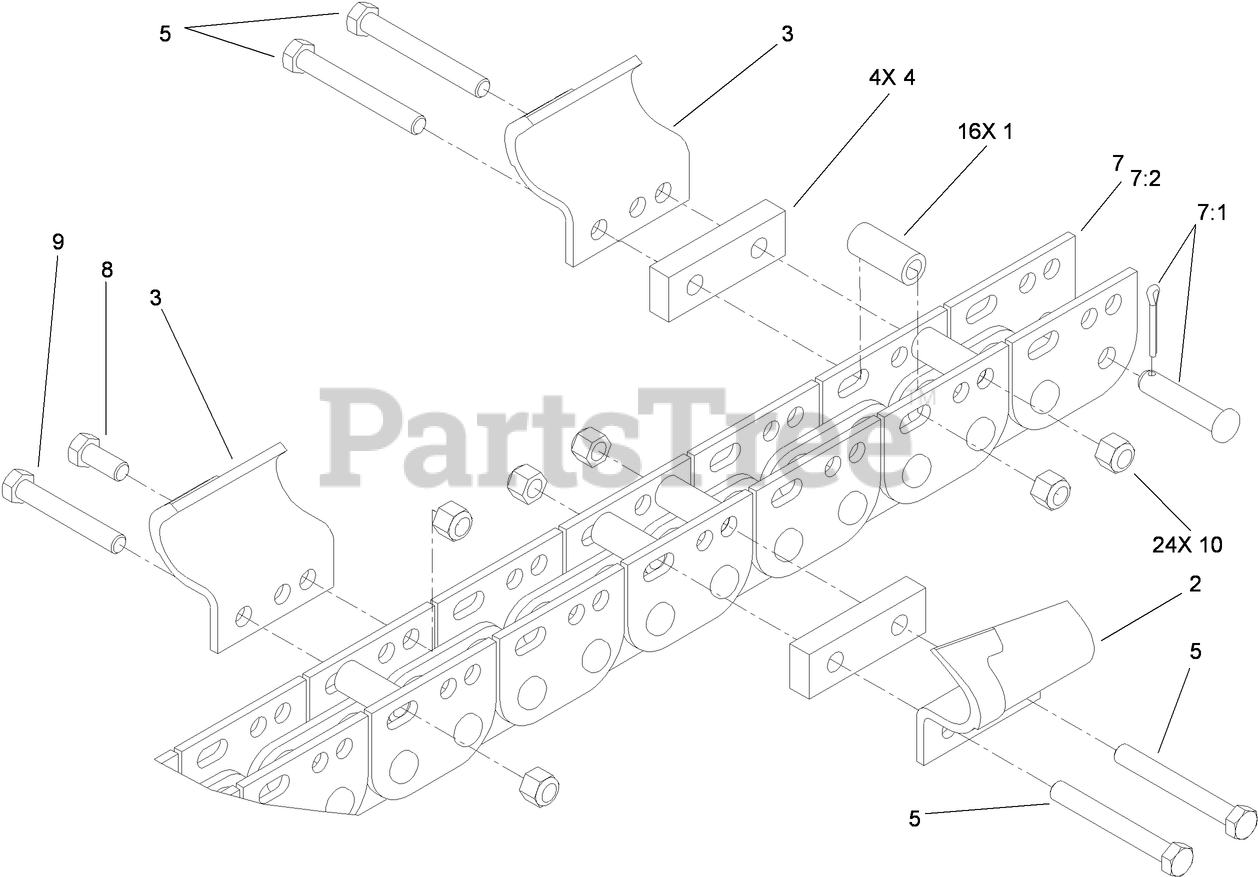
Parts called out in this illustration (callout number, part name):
1	SPACER-TUBE
2	TOOTH-SOIL, LH
3	TOOTH-SOIL, RH
4	SPACER-CUT, 5 INCH
5	SCREW-HH
7	CHAIN-BARE, 24 STATION
7:1	PIN-CONNECTING,
7:2	KIT-REPAIR, LINK
8	SCREW-HH
9	SCREW-HH
10	NUT-LOCK
